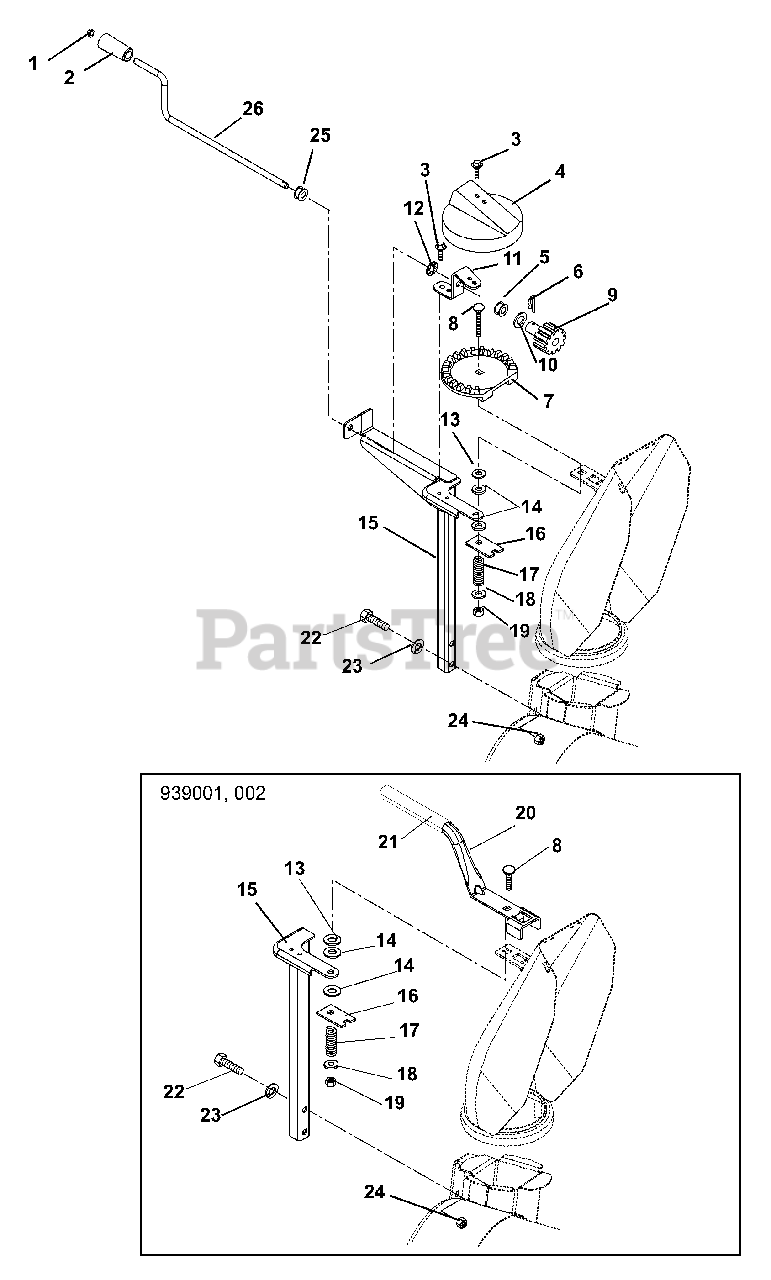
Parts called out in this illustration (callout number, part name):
1	CAP, 3/8 ROD YWZC
2	KNOB, CHUTE CRANK
3	@SCR-TAP .25-20X.50 HWH TR YWZ
4	GEAR COVER
5	BUSHING, POLYLINER-.63 SNAPIN
6	PIN, SPRING CLIP
7	CHUTE GEAR
8	@BLT-RDHDSQNK .38-16X2.50 G5YZ
9	BRACKET W/PINION GEAR
10	WSHR-THRST .625 X 1.0 X .03
11	BRACKET, PINION GEAR
12	PUSHNUT .625
13	WSHR-FL-STL .380X1.50X.062 YWZ
14	FRICTION WASHER
15	WLDMT, CHUTE PEDESTAL W/CRANK
16	PLATE, FRICTION
17	SG-COMP .187X.56X1.62
18	@WSHR-FL-STL.406X.812X.065 YWZ
19	@NUT-LK-CTR .38-16 YWZC
20	HANDLE, CHUTE ROTATION
21	GRIP, CHUTE HANDLE, ORANGE
22	@BLT-HEX .38-16X1.75 GR5 YWZC
23	@WSHR-LK .38X.094 REG YWZC
24	@NUT-LK-TOP-FLG .38-16 YWZC
25	BUSHING, POLYLINER-.38 SNAPIN
26	CRANK, CHUTE
